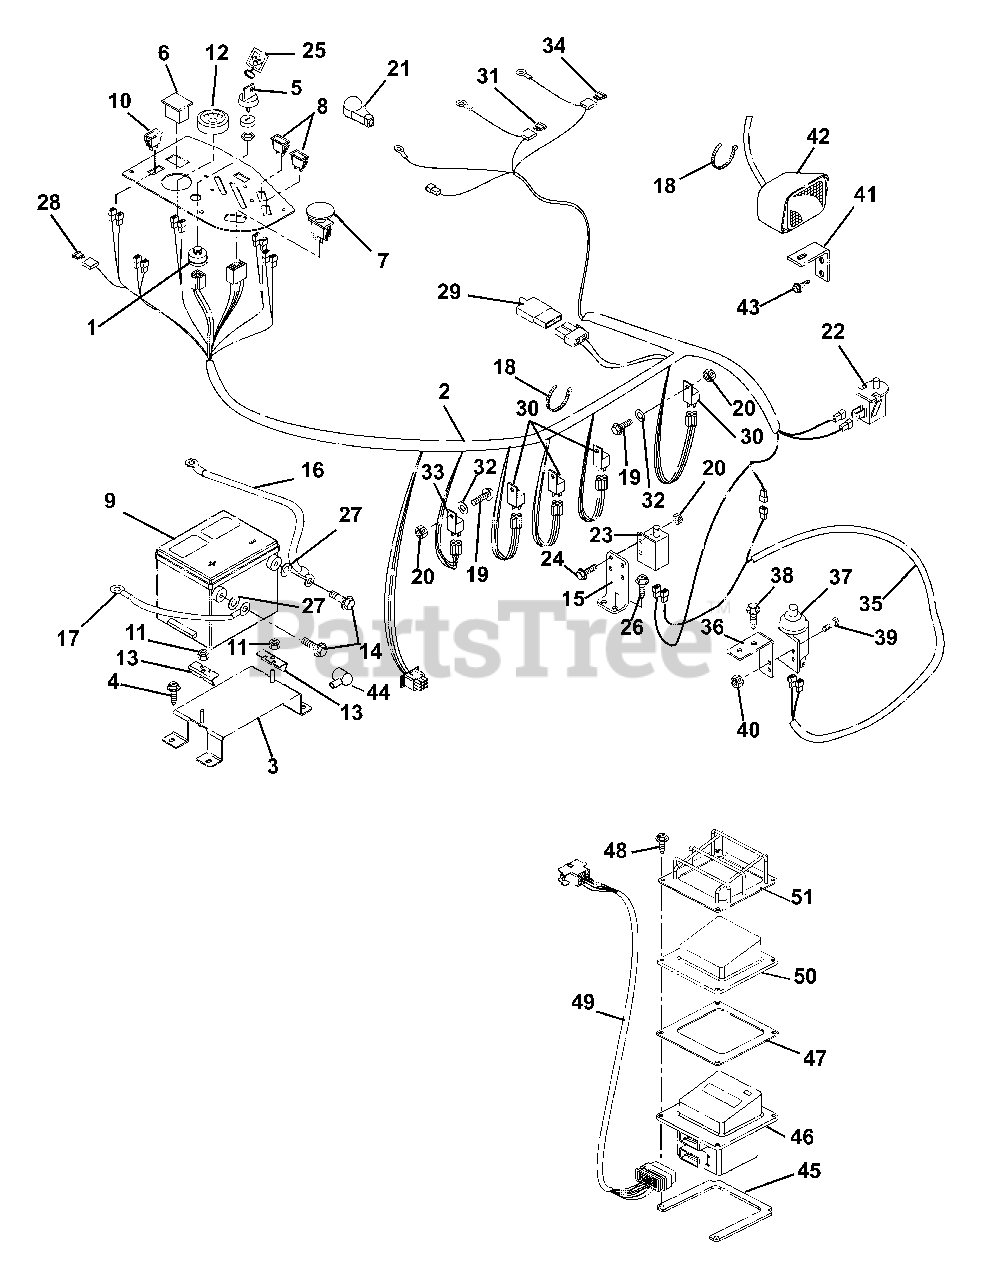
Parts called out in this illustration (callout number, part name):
1	SWITCH, IGNITION (DIESEL)
2	HARNESS, HORZ. L/C(DIESEL)
3	WMT, BATTERY SUPPORT
4	@SCR-TAP .38-16X.75 HWH TR YWZ
5	KEY, W/ SHIELD
6	PLUG, HOUR METER
7	SWITCH, CLUTCH
8	LIGHT,INDICATOR
9	BATTERY, GROUP 70 450 CCA 35 A
10	SWITCH, 2 POLE/ROCKER
11	@NUT-LK-TOP-FLG .31-18 YWZC
12	GAUGE, TEMPERATURE
13	BRKT, BATTERY HOLD-DOWN
14	BATT TERMINAL SCREW
15	MOUNT, SAFETY SWITCH
16	CABLE, POS BATT 4 GA X 45
17	CABLE, NEGATIVE BATTERY 49.00
18	CABLE TIE LG 5-1/2
19	@SCR-MCH 10-24X.75 HWH YWZC
20	@NUT-LK-NYL 10-24 W/INSRT YWZC
21	BOOT, EYELET TERMINAL
22	SWITCH- SNAP MTG N.O.
23	SWITCH- SINGLE POLE N.O.
24	@SCR-MCH 10-24X.75 HWH YWZC
25	KEY CHAIN
26	@SCR-TAP .25-20X.50 HWH TR YWZ
27	@WSHR-FL-STL.38X.875X.083 YWZC
28	FUSE, 15 AMP.
29	DIODE, CONNECTOR SHELL
30	RELAY
31	FUSE, 30 AMP.
32	@WSHR-FL-STL.250X.56X.049 YWZC
33	Pre-Heat Timer
34	FUSE, 50 AMP (MAXI FUSE)
35	HARNESS, WIRE ADAPTER CE
36	MOUNT - SWITCH
37	SWITCH-SINGLE POLE N.O.W/COVER
38	@SCR-TAP .31-18X.50 HWH TR YWZ
39	@SCR-MCH 10-24X.75 HWH YWZC
40	@NUT-LK-NYL 10-24 W/INSRT YWZC
41	BRACKET, HEADLIGHT MTG
42	HEADLIGHT
43	@SCR-TAP .38-16X.50 HWH TR YWZ
44	BOOT, EYELET TERMINAL
45	SPACER, ENCLOSURE MTG. (BTM)
46	ASSY, EYE-Q
47	GASKET-EYE Q
48	SCR-MCH 10-24X1.0 SL PAN BLACK
49	HARNESS - EYE-Q
50	GUARD, ELEMENT
51	GUARD, VINYL EYE-Q
